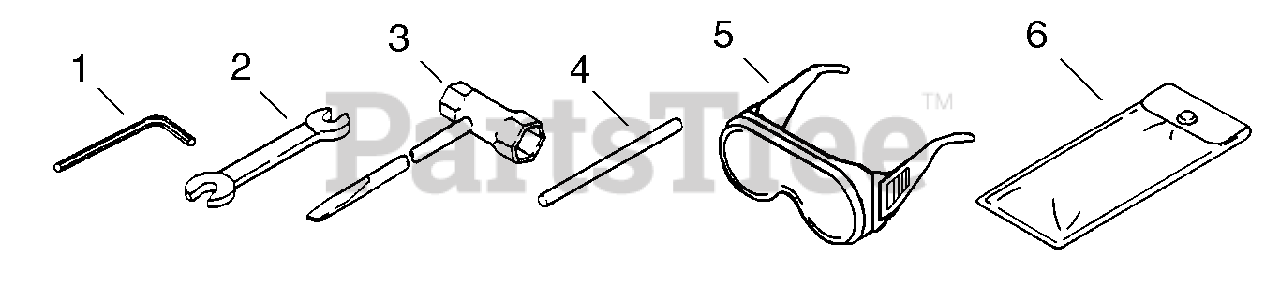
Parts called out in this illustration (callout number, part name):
1	WRENCH, ALLEN 4 MM
2	SPANNER 8×10
3	T-WRENCH 17x-19 L200
4	TOOL, LOCKING 5×120 MM
5	GLASSES, SAFETY
6	BAG, TOOL
